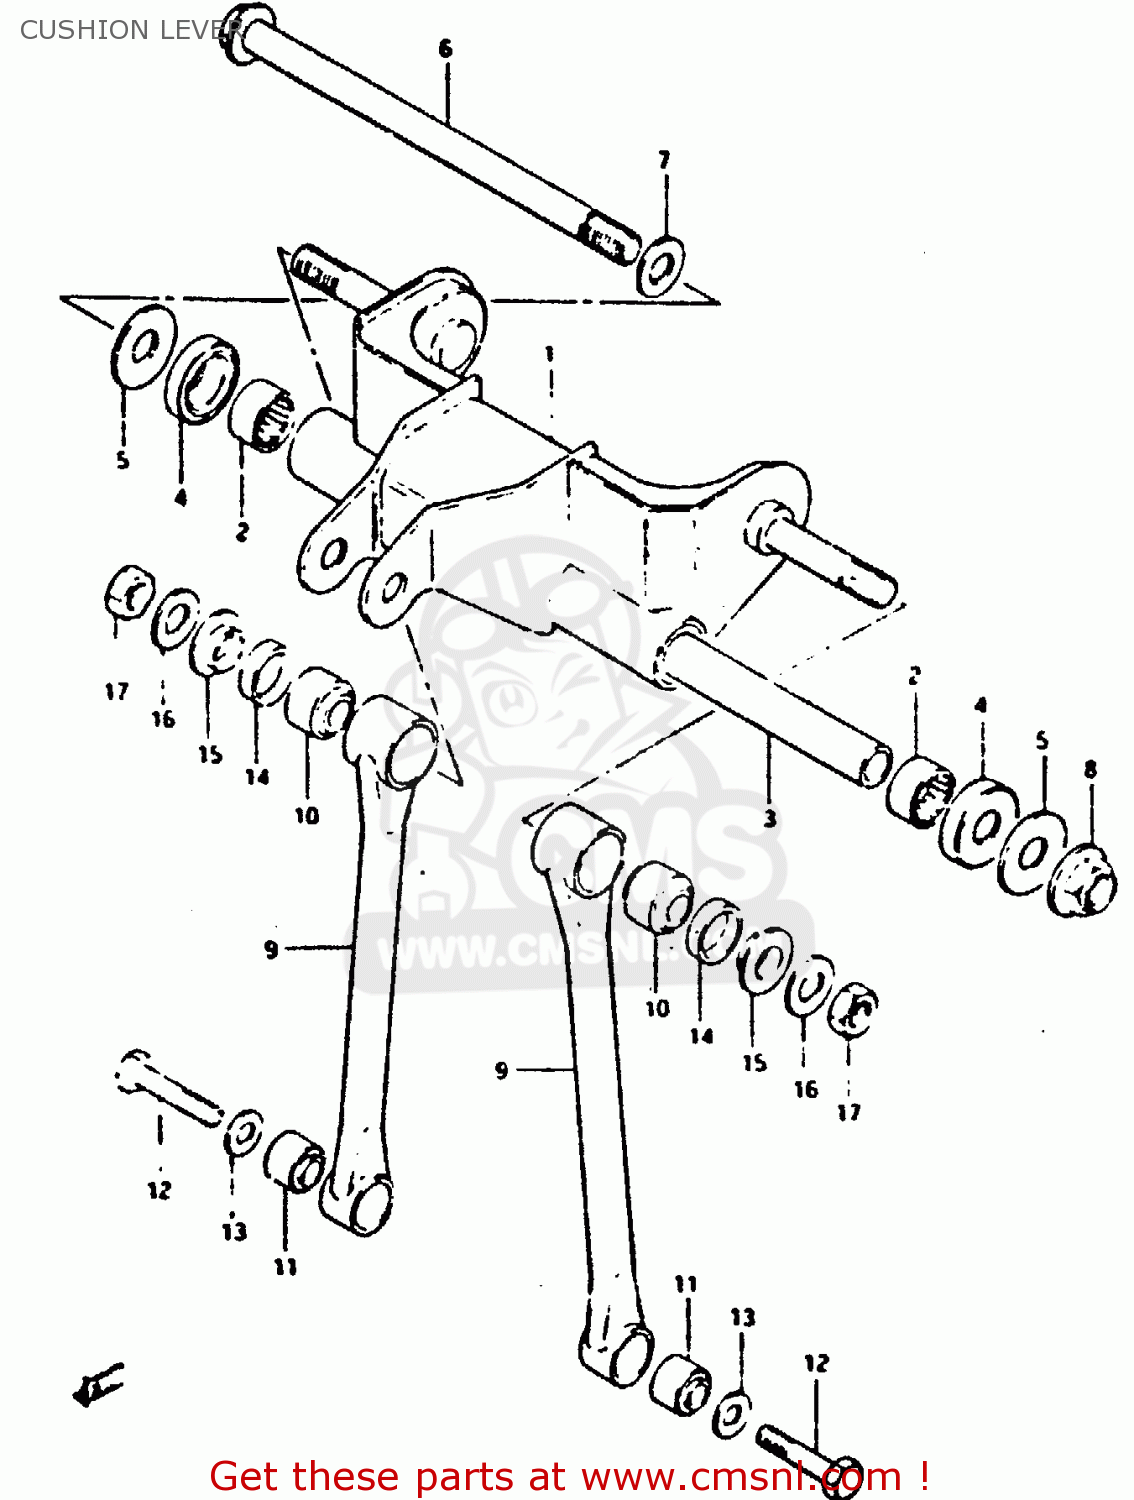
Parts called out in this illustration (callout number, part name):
1	ROD SET,REAR CUSHION LEVER
2	ROLLER BEARING (17X24X2
3	SPACER,REAR CUSHION LEVER
4	COVER,RR SWGARM DUST SEAL
5	WASHER
6	SHAFT,REAR CUSHION LEVER
7	WASHER
8	NUT
9	LEVER SET,REAR CUSHION
10	BEARING
11	BUSH
12	BOLT
13	WASHER
14	DUST SEAL, UPPER
15	SPACER,REAR SHOCK ABSORBER
16	WASHER
17	NUT
